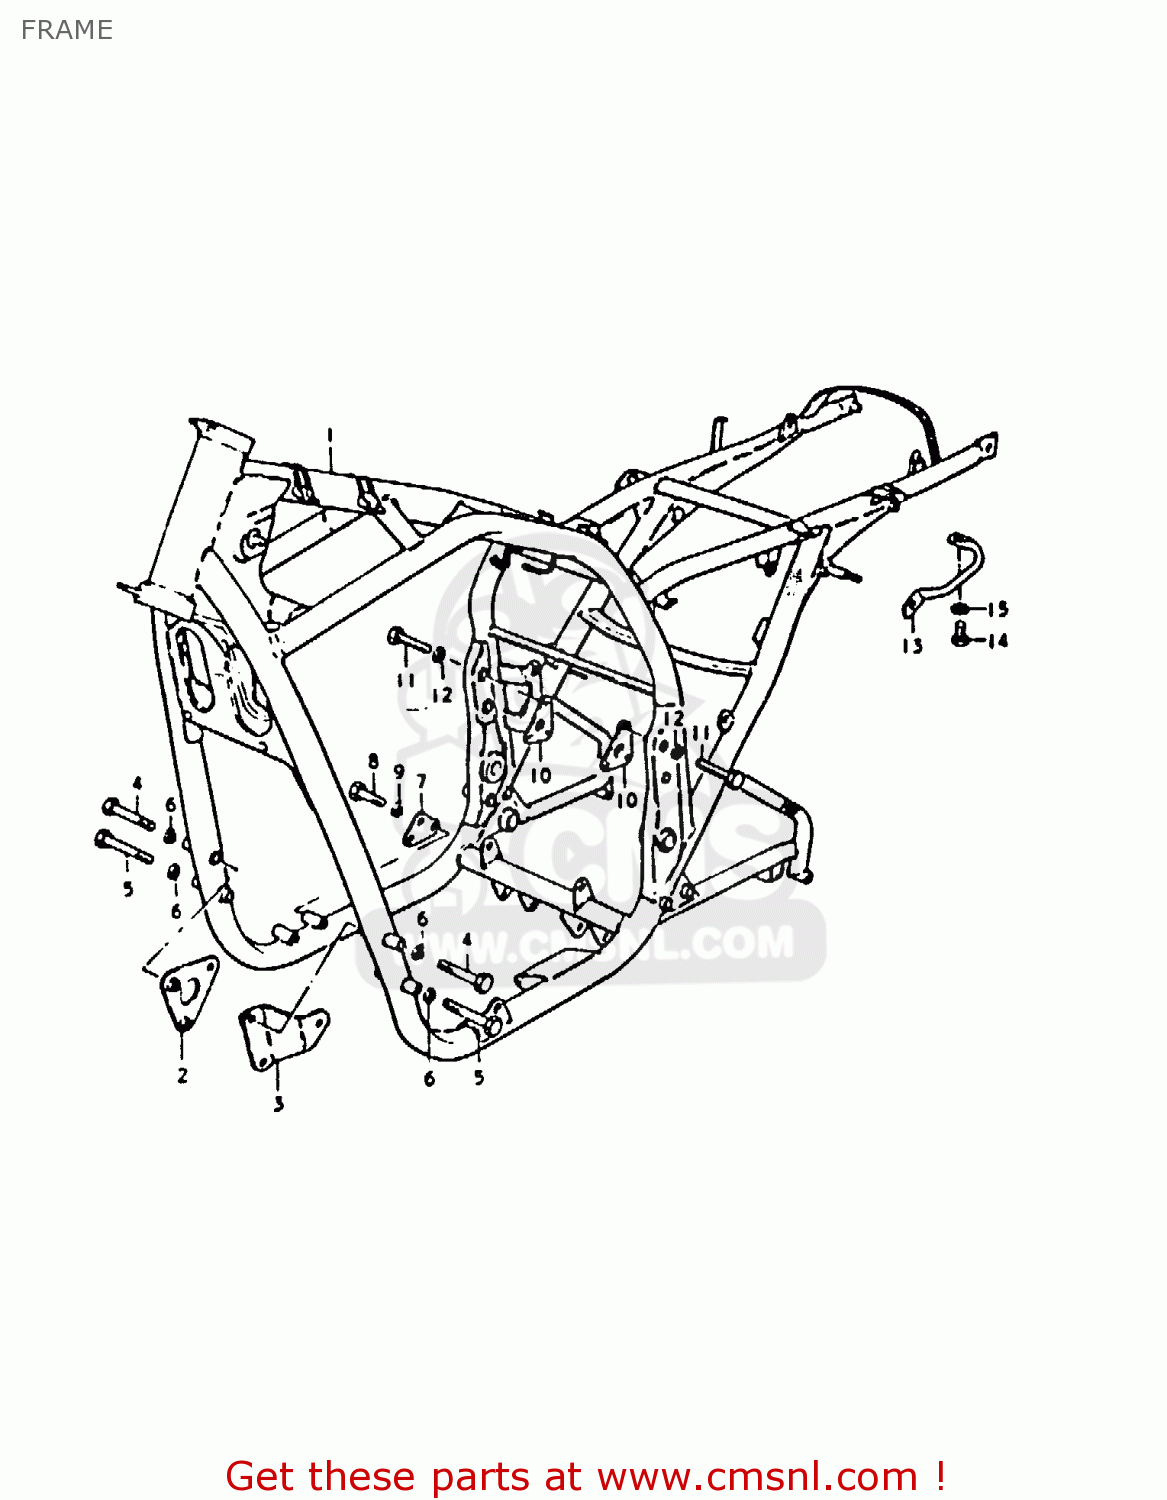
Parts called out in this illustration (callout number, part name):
1	FRAME
2	PLATE,ENGINE MOUNTING
3	PLATE,ENGINE MOUNTING
4	BOLT
5	BOLT
6	LOCK WASHER
7	PLATE,ENGINE MOUNTING
8	BOLT
9	LOCK WASHER
10	PLATE,ENGINE MOUNTING
11	BOLT
12	LOCK WASHER
13	GRIP,FRAME
14	BOLT
15	WASHER
